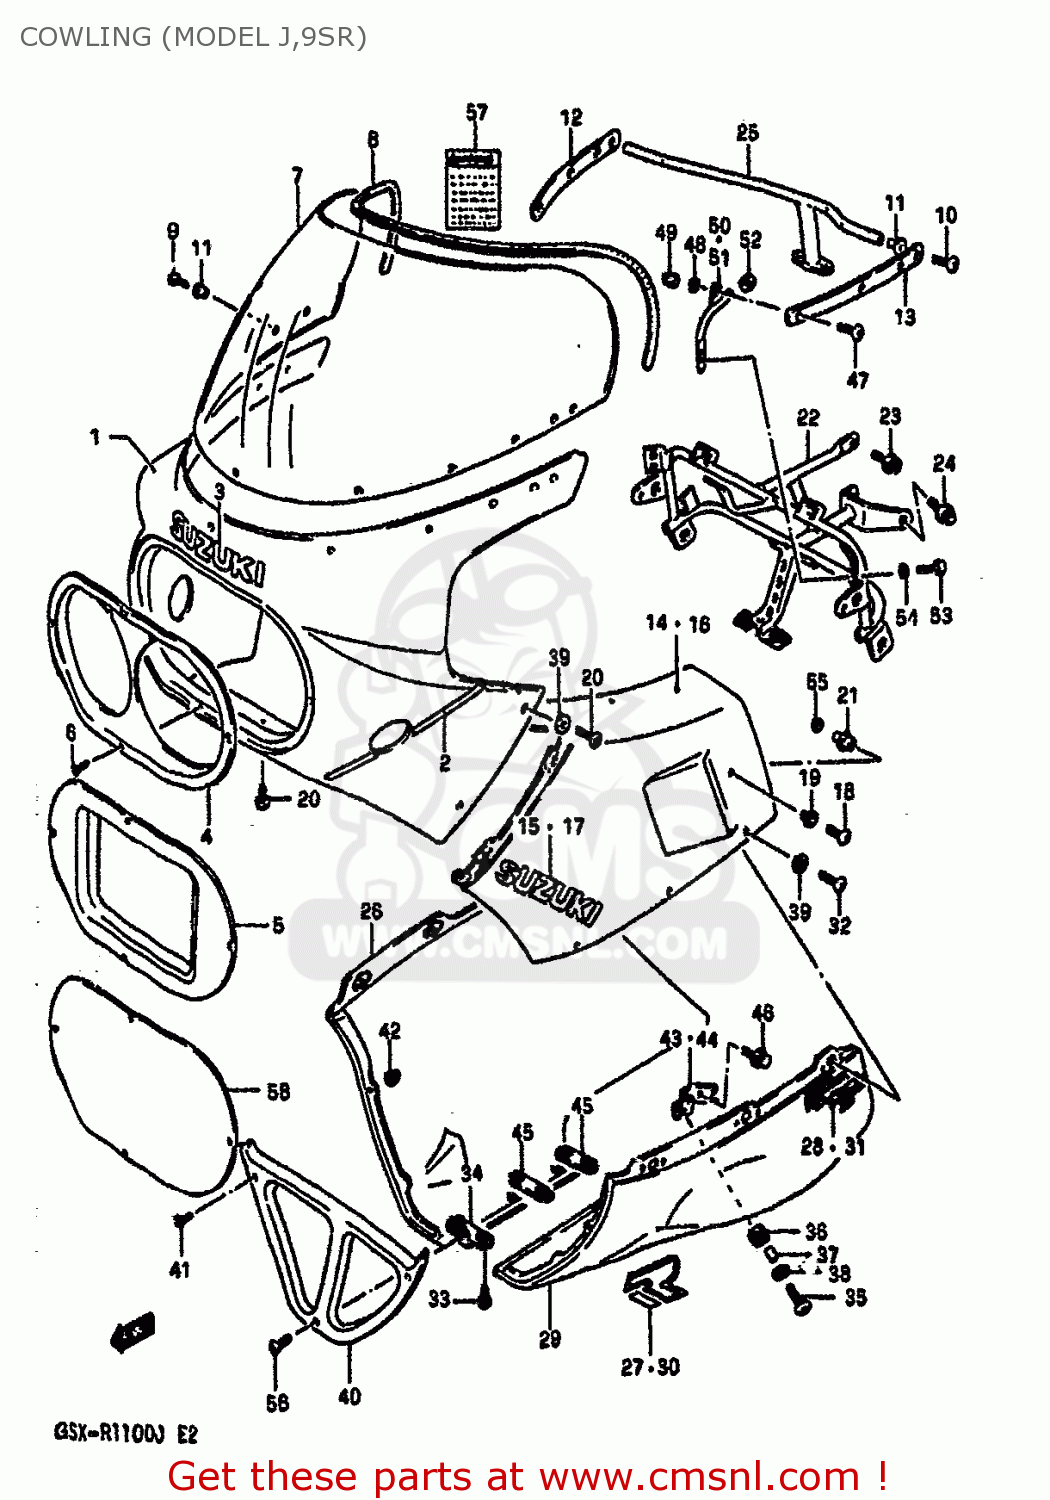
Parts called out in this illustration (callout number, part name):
1	BODY ASSEMBLY,COWLING
2	TAPE SET,COWLING,UPPER
3	EMBLEM,COWLING,UPPER (W)
4	COVER,COWLING,FRONT
5	COVER,FRONT (BLUE)
6	SCREW
7	WINDSCREEN
8	MOLDING
9	SCREW(5X14)
10	SCREW(5X18)
11	NUT,COWLING SCREEN
12	PLATE,RR VIEW MIRROR,R
13	PLATE,RR VIEW MIRROR,L
14	COVER,COWLING SIDE,RIGHT
15	EMBLEM
16	COVER,COWLING SIDE,LEFT
17	EMBLEM
18	SCREW(6X12)
19	WASHER
20	SCREW(6X16)
21	CUSHION,COWLING
22	BRACE,COWLING FR
23	BOLT
24	BOLT
25	BRACE,COWLING BODY RR
26	COVER,COWLING,LOWER,RIGHT
27	EMBLEM,COWLING UNDER
28	EMBLEM,COWLING,UNDER
29	COVER,COWLING,LOWER,LEFT
30	EMBLEM,COWLING UNDER
31	EMBLEM,COWLING,UNDER
32	SCREW(6X16)
33	SCREW(6X16)
34	BRACE,COWLING LWR COVER
35	SCREW(6X20)
36	CUSHION
37	SPACER
38	WASHER(6.5X18X1)
39	WASHER
40	COVER,COWLING,LOWER,FRONT
41	SCREW(5X14)
42	NUT
43	BRACE,COWLING LWR,R
44	BRACE,COWLING LWR,L
45	BRACE,COWLING LWR COVER RR
46	BOLT
47	SCREW(6X16)
48	WASHER,LOCK
49	NUT 6MM
50	BRACE,MIRROR,R
51	BRACE,MIRROR,L
52	PLUG(OD:12)
53	BOLT 6X16
54	WASHER,LOCK
55	WASHER
56	SCREW(6X16)
57	LABEL (WARNING SCREEN)
58	COVER,HEADLAMP
